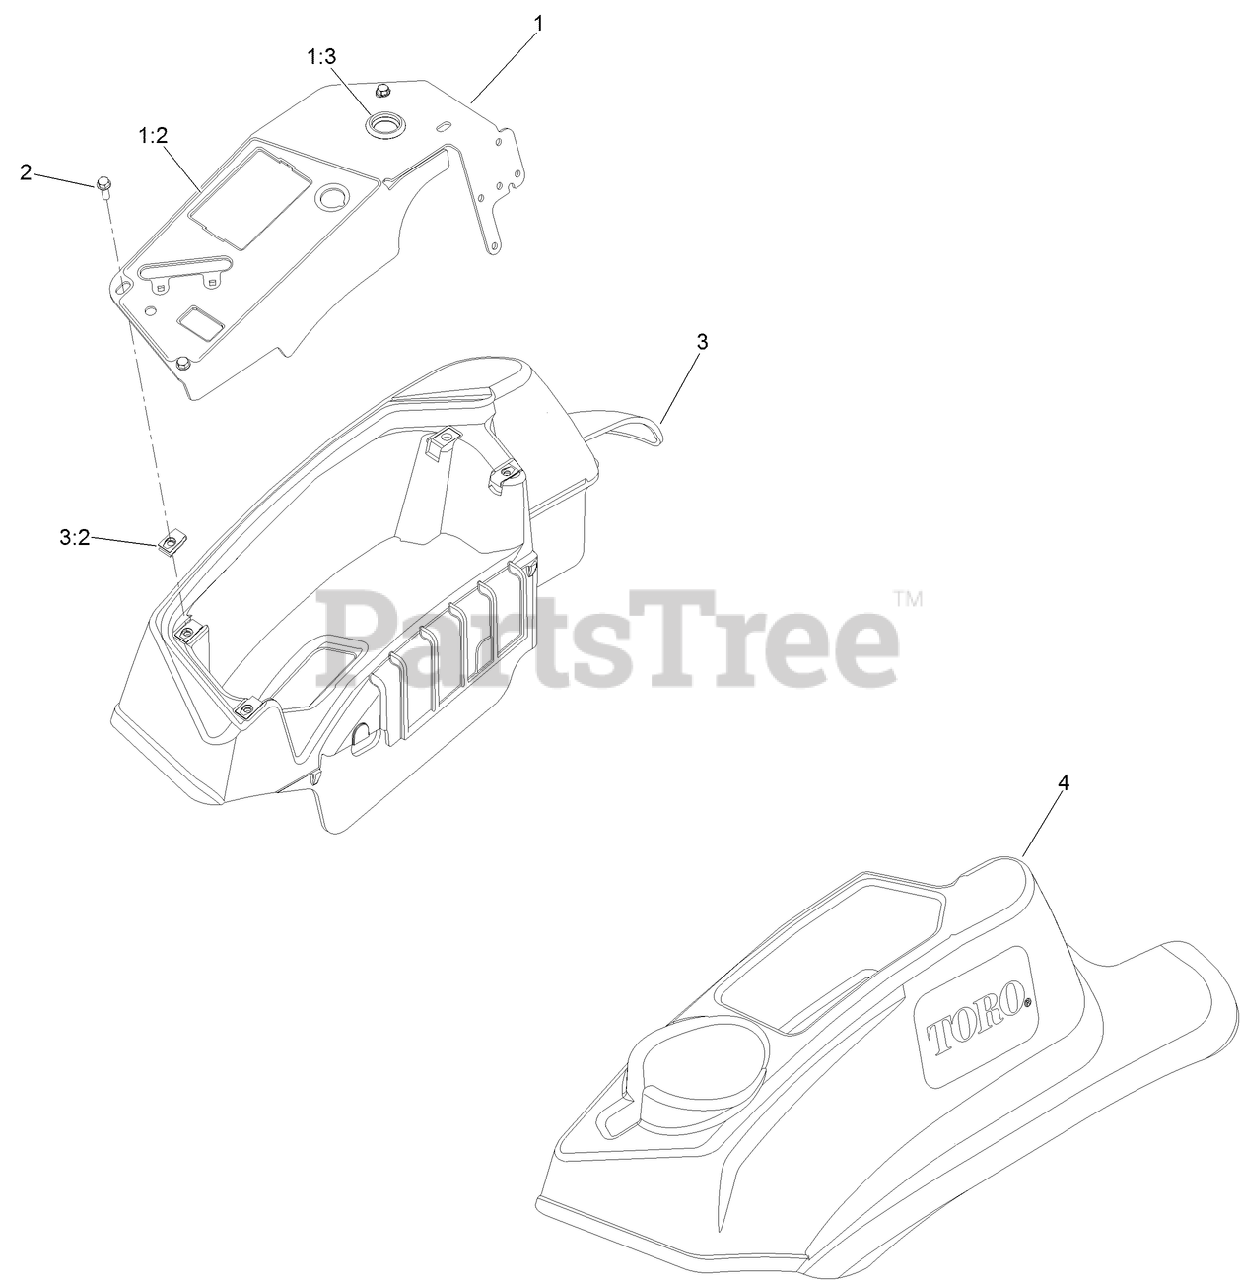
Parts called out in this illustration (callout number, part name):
1	CONTROL PANEL ASM
1:2	DECAL-PANEL, CONTROL
1:3	PLUG-PLASTIC
2	SCREW-HWH
3	RH CONSOLE ASM
4	CONSOLE-LH
